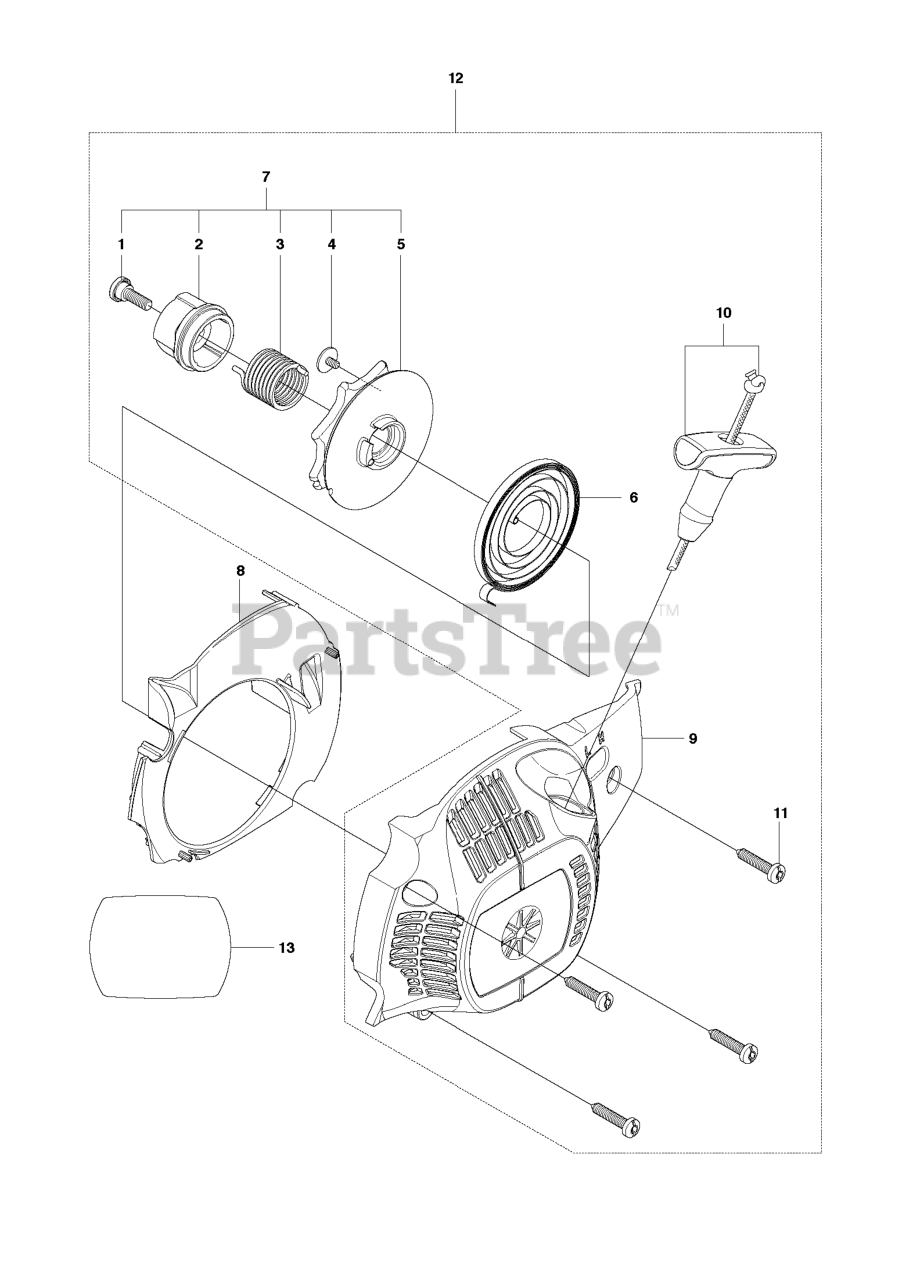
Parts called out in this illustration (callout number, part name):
1	SCREW SHOULDER
2	HUB STARTER EPS
3	SPRING EPS
5	PULLEY STARTER EPS
6	SPRING STARTER
7	KIT EPS STARTER
9	FAN HOUSING
10	STARTER ROPE W/HANDLE
11	SCREW M5.38-14X22.225MM
12	KIT COMPLETE EPS
